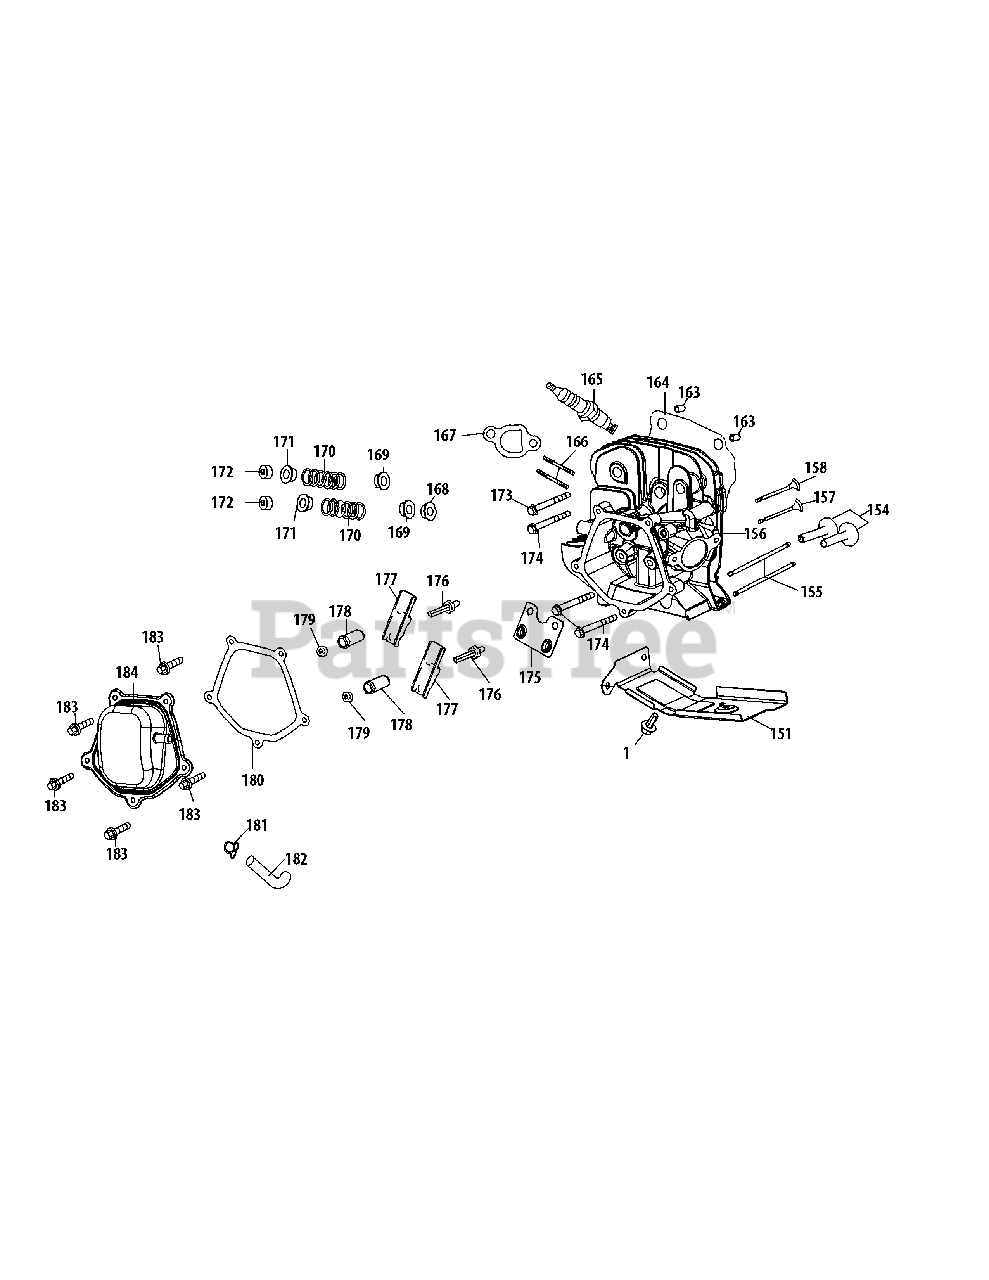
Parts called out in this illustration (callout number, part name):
1	BOLT M6×12
154	TAPPET
155	PUSH ROD
156	CYLINDER HEAD
157	INTAKE VALVE
158	EXHAUST VALVE
159	GOVERNOR ARM SHAFT
160	GOVERNOR SEAL
161	WASHER 8×20×0.8
162	COTTER PIN
163	DOWEL PIN 12×20
164	GASKET, CYLINDER HEAD
165	SPARK PLUG/F6RTC
166	STUD M8×48.5
167	EXHAUST PIPE GASKET
168	VALVE SEAL (INTAKE)
169	VALVE SPRING RETAINER(INTAKE)
170	VALVE SPRING
171	VALVE SPRING RETAINER (EXHAUST)
172	EXHAUST LASH CAP
173	BOLT M10×1.25×65
174	BOLT M10×1.25×87
175	PUSH ROD GUIDE
176	BOLT,PIVOT
177	ROCKER ARM
178	ADJUSTING NUT ,VALVE
179	NUT, PIVOT LOCKING
180	VALVE COVER GASKET
181	BREATHER HOSE CLAMP
182	BREATHER HOSE
183	VALVE COVER BOLT
184	VALVE COVER
